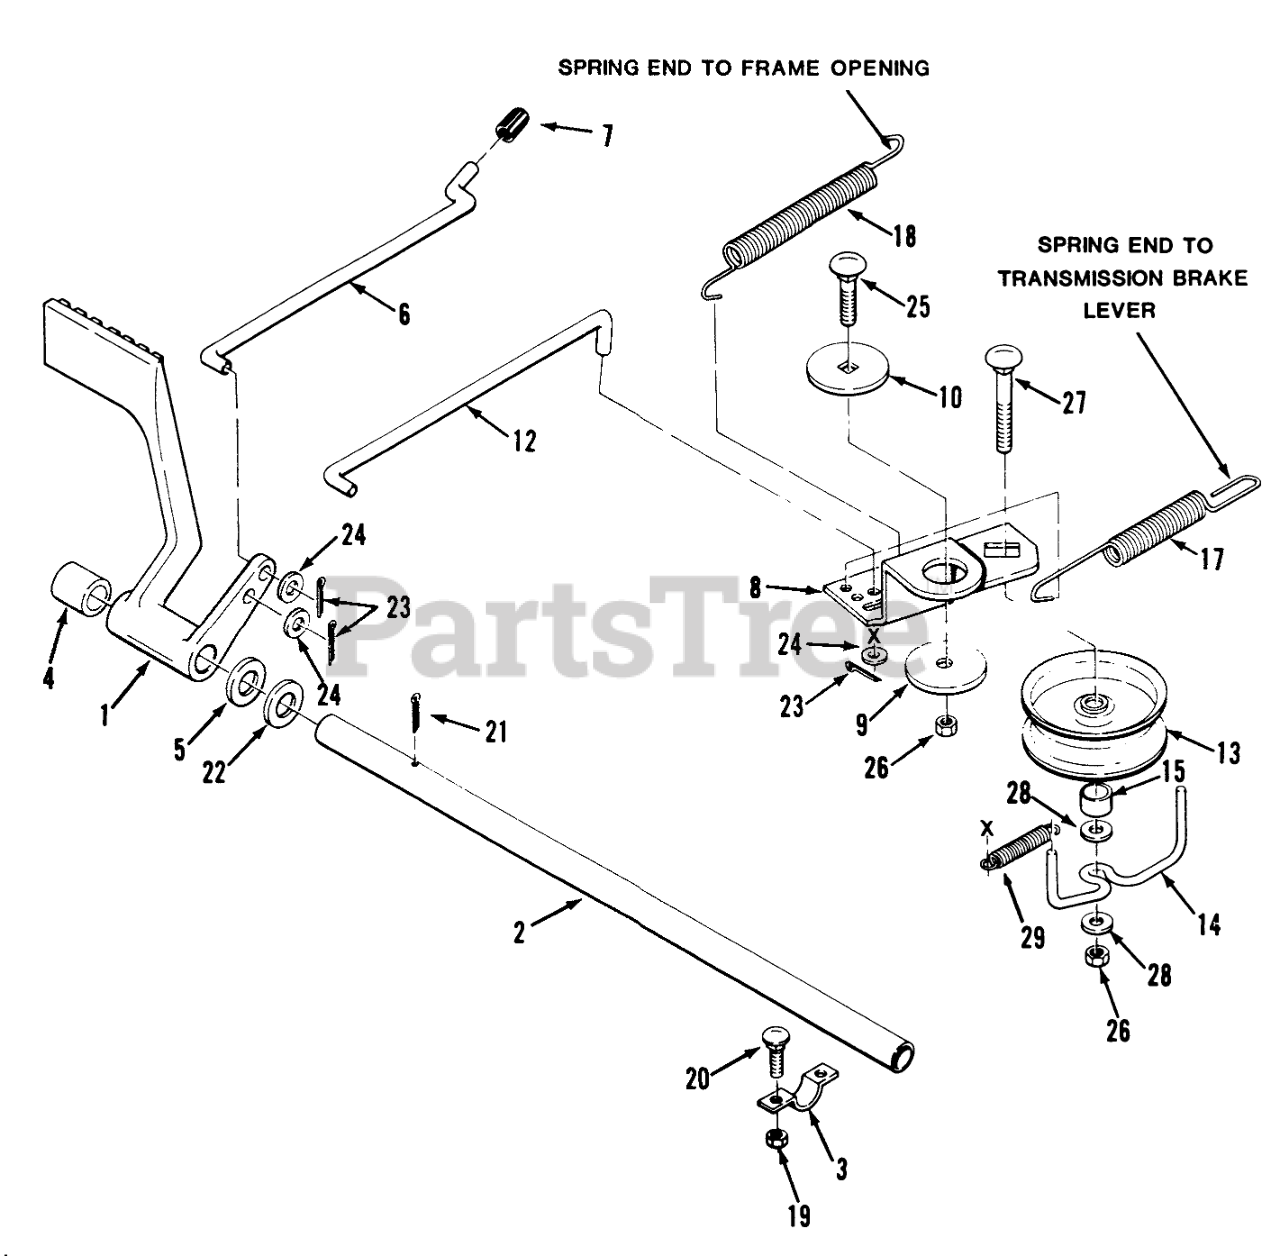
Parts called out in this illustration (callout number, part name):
1	PEDAL BRAKE R
2	SHAFT PEDAL
3	CLAMP
4	SPACER
5	WASHER-WAVE
6	Lock Rod
8	ARM-IDLER R
9	BUSHING
10	WASHER-BEARING
12	ROD-CLUTCH/BRAKE B
13	PULLEY IDLER
14	GUIDE-BELT
15	SPACER
17	SPRING - BRAKE
18	SPRING - CLUTCH
19	NUT-LOCK, NI
20	SCREW-CARR
21	PIN-COTTER
22	Washer
23	PIN-COTTER
24	WASHER-PLAIN
25	BOLT-CARR
26	NUT-LOCK, NI
27	SCREW-CARR
28	WASHER-FLAT
29	EXTENSION-SPRING
